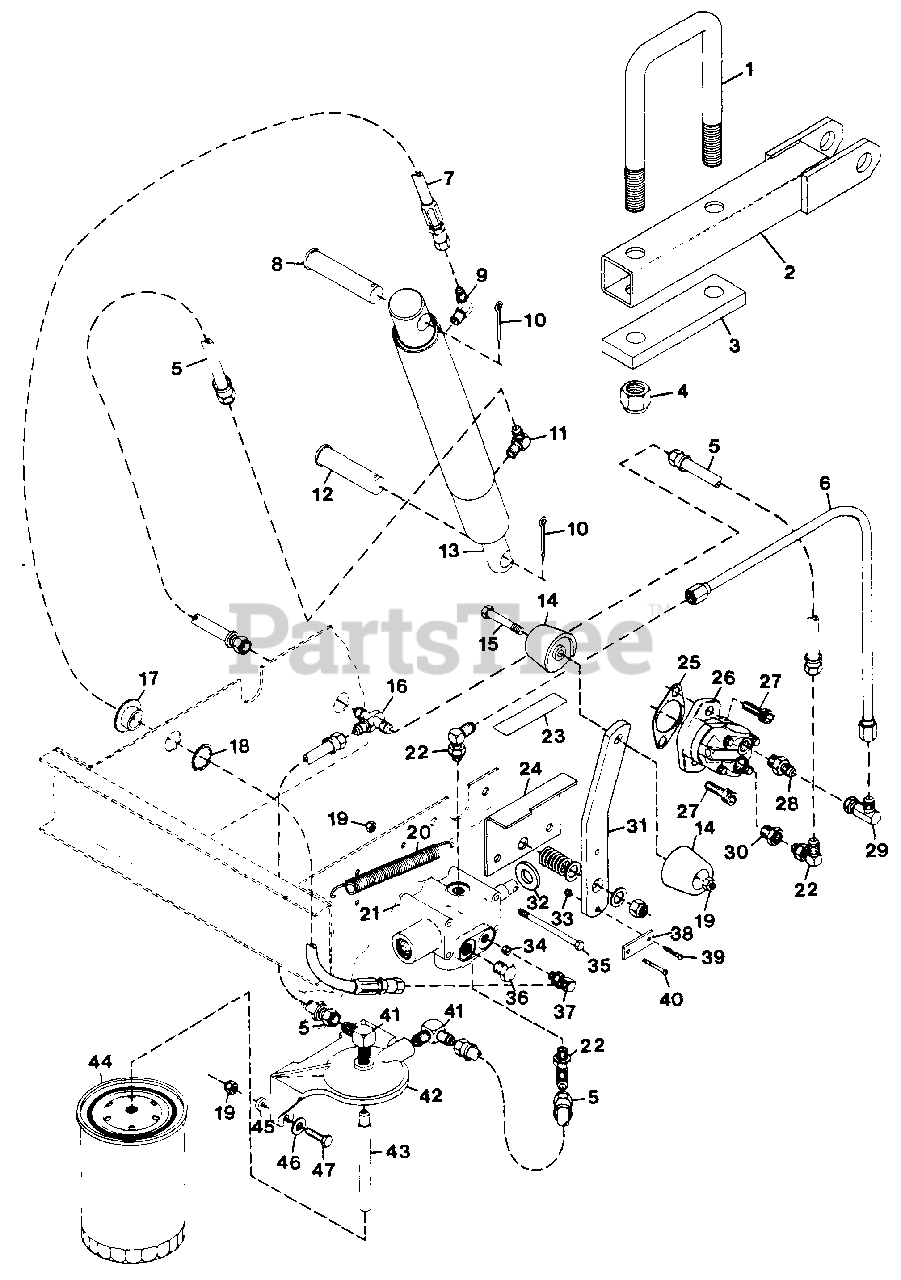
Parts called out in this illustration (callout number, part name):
1	U-Bolt
2	Arm, Lift
3	Plate, Axle
4	Nut, Lock 5/8-18
5	Hose, Hydraulic
6	Line, Hydraulic Pump to Valve
7	Hose, Hydraulic
8	Pin, Clevis
9	Adaptor, PH 2103-4-4
10	Pin, Cotter .125x1.25
11	Adaptor, Hydraulic
12	Pin, Clevis
13	Cylinder, Hydraulic
14	Knob, Control
15	Bolt, Hex 1/4-20x1.50
16	Adaptor, Tee
17	Bushing, Nylon .76x1x.6 Flange
18	Ring, Rtng. Int. Tooth 1.000 Sft.
19	Nut, Lock 1/4-20
20	Spring, Extension 5.5x.5x20 Rate
21	Valve, Hydraulic
22	Adaptor, 2503-6-6
23	Decal, Hydraulic Lift
24	Bracket, Lift
25	Gasket, Cover Plate
26	Pump, Hydraulic
27	Screw, Cap 3/8-16 HSKTHD
28	Adaptor, 0503-8-6
29	Adaptor, 3903-6-6
30	Bushing
31	Lever, Lift
32	Spacer
33	Nut, Lock 10-24
34	Plate, Flow Restriction
35	Bolt, Hex 1/4-20x2.75
36	Plug, PH 05PO-4
37	Adaptor, 2503-4-4
38	Strap, Valve
39	Screw, Mach. 10-24x.75 Rd Hd
40	Screw, Mach. 10-24x1.00 Rd Hd
41	Adaptor, 2503-6-4
42	Bracket, Oil Filter
43	Tube, Oil Pickup
44	Filter, Spin-On
45	Spacer
46	Washer, Flat .281x.625x.065
47	Bolt, Hex 1/4-20x1.25
